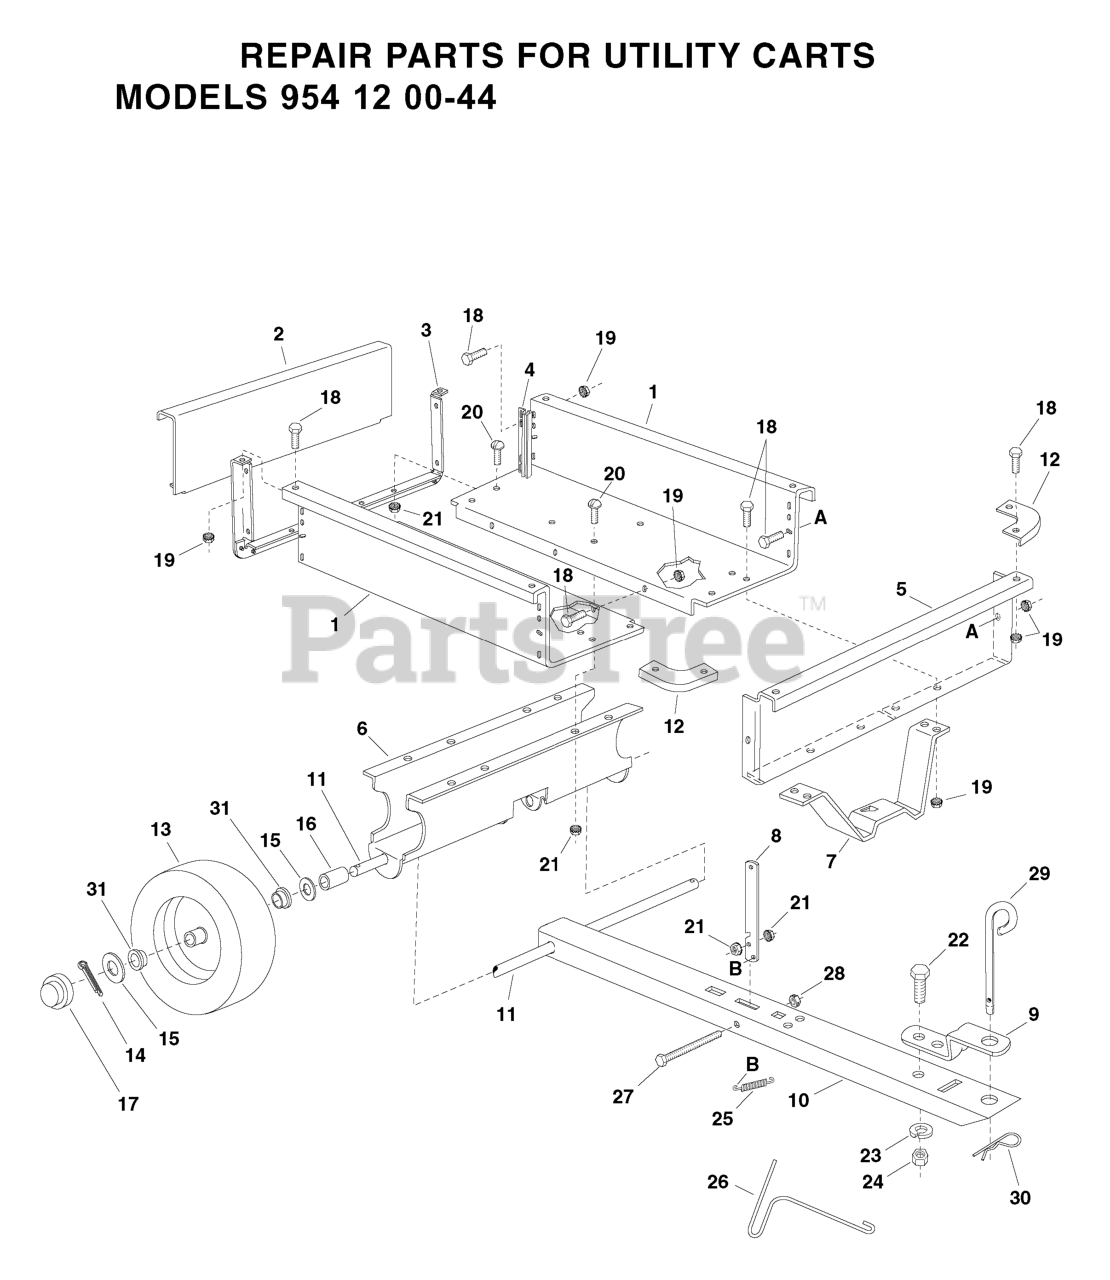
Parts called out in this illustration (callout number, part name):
2	PANEL, REAR
5	PANEL, FRONT
9	HITCH BRACKET
18	Bolt, Hex 1/4-20 x 1/2" Lg.
20	BOLT
23	Spring Washer
29	Pin, Hitch
